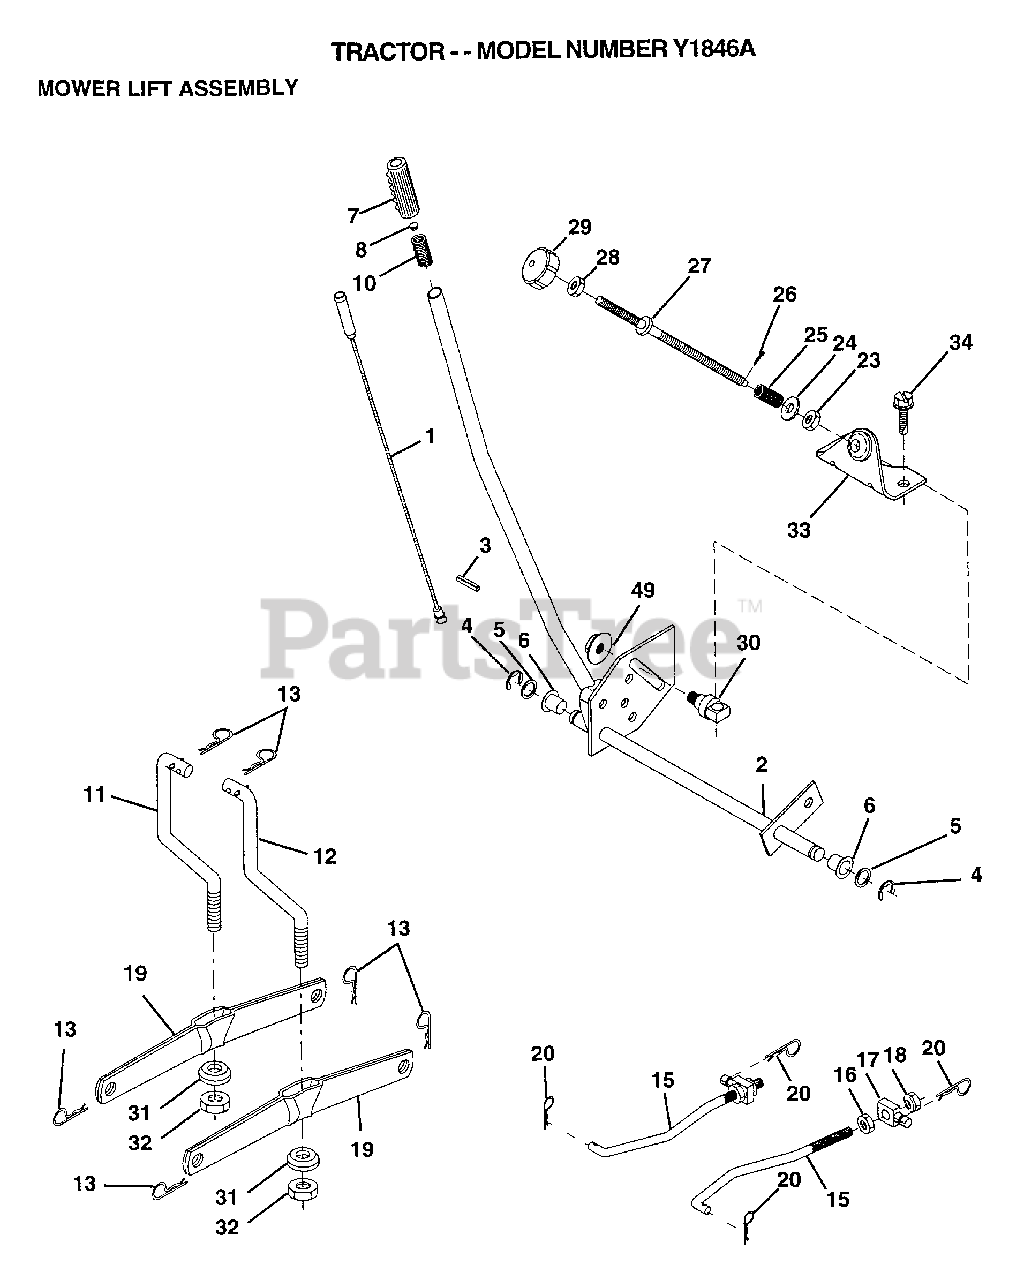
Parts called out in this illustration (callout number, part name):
1	WIRE ASM
2	HANDLE.LIFT.LH.
3	PIN GROOVE
5	WASHER
6	NYLON BEARING
7	GRIP
16	NUT
17	TRUNION
18	NUT.LK.W/WSH.1/2.
19	ARM SUSP REAR
20	RETAINER.SPRING
23	NUT T
24	WASHER
25	SPRING T
28	NUT HEX JAM 3/8-16 UNC
30	TRUNNION
31	BEARING PVT LH
32	NUT.CROWNLOCK.3/8
33	BRACKET STOP INF
34	SCREW LT
